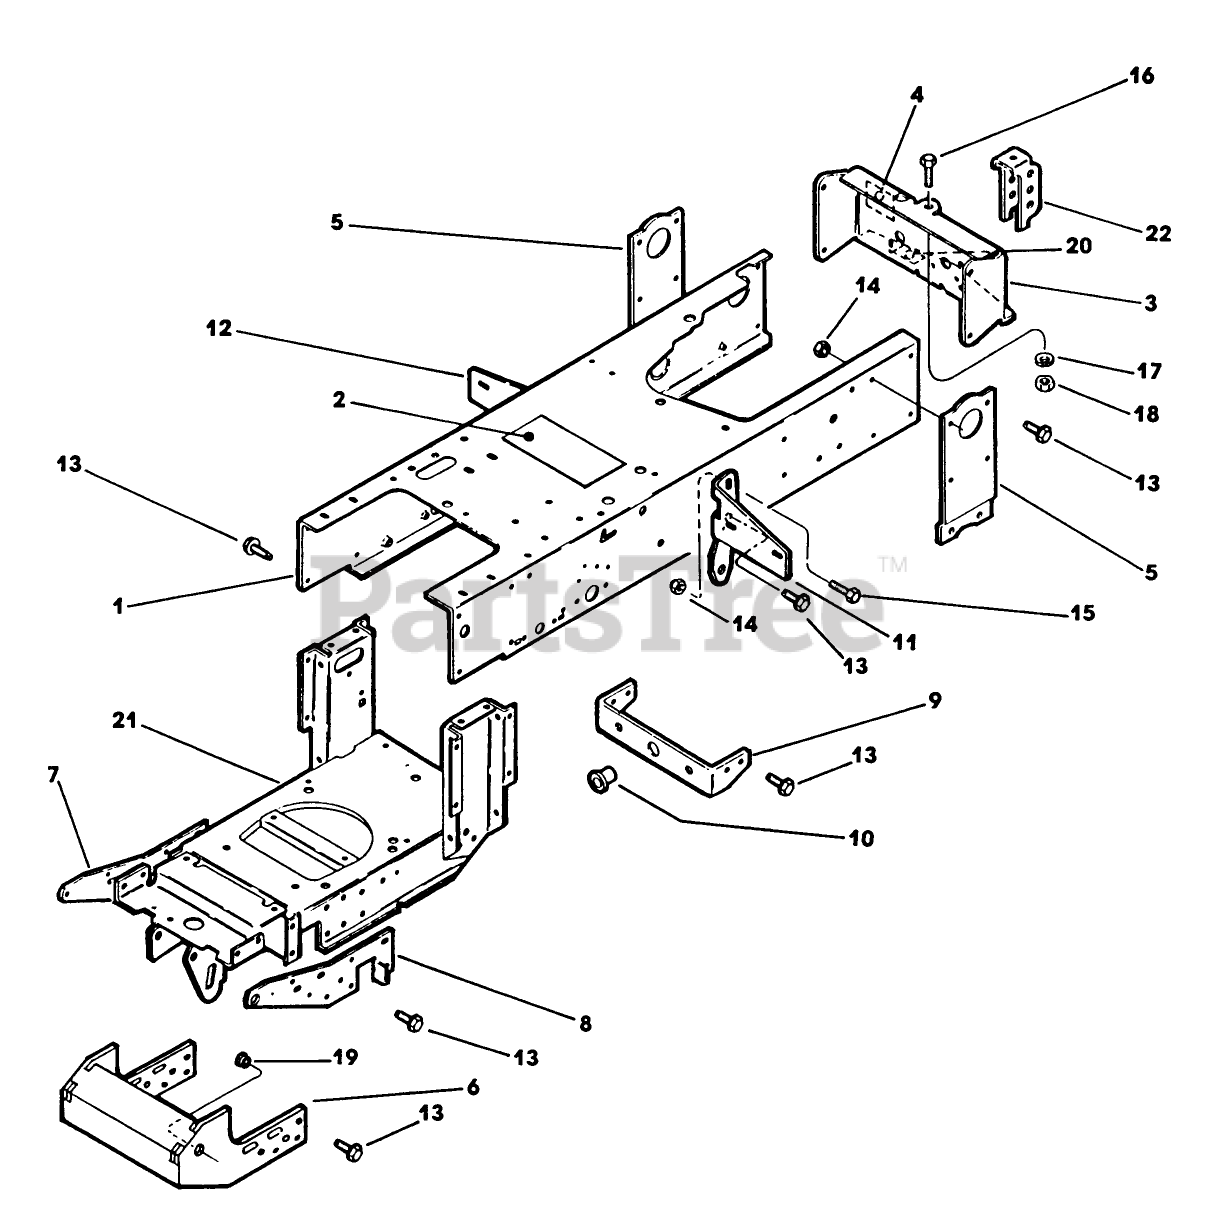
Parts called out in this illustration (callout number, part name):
12	SUPPORT - RH
14	NUT
15	SCREW
19	BEARING-NYLINER
